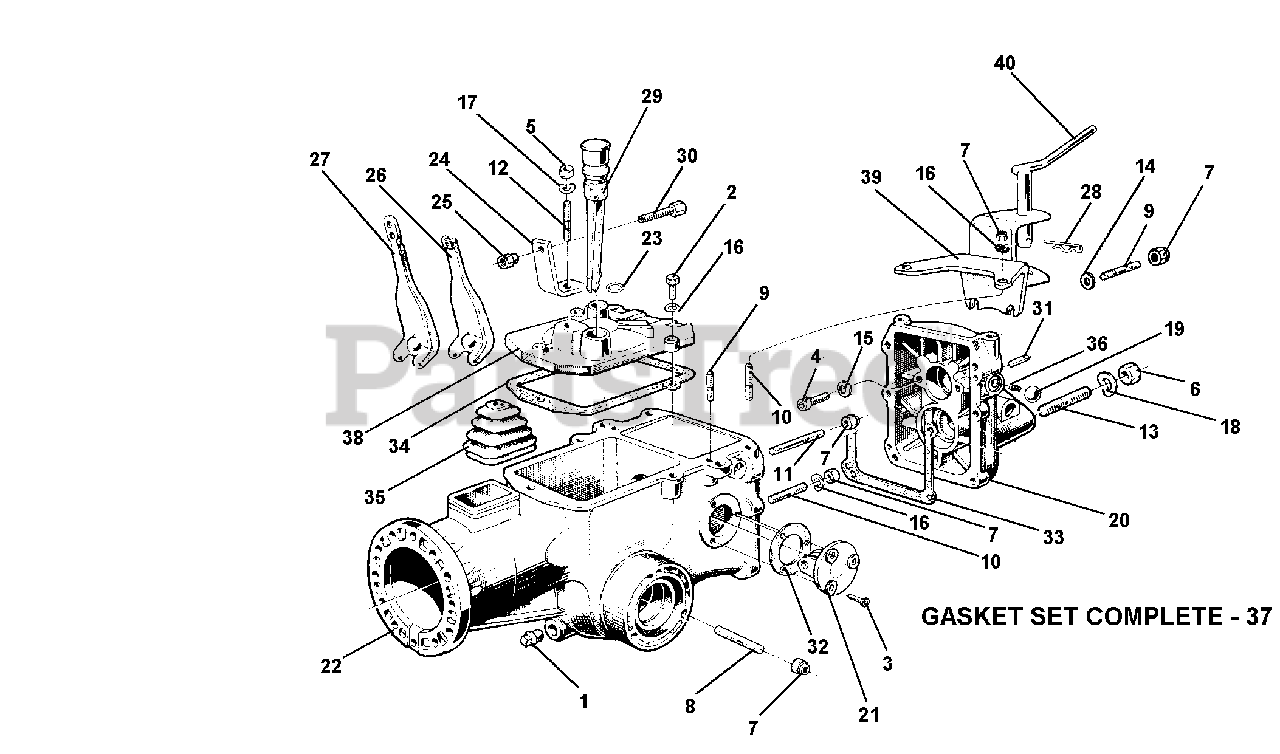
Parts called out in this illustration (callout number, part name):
1	PLUG 1/4 GAS
2	SCREW TE M8 X 30
3	SCREW M6 X 16
4	SCREW TCCEI M8 X 12
6	NUT M12 X 1.25 UNI 5587 6S
7	NUT, SELF LOCKING M8
8	STUD M8 X 46 X 20 X 12
9	STUD M8 X 38 X 14 X 20
10	STUD M8 X 46 X 16 X 16
11	STUD M8 X 58 X 16 X 16
12	STUD M10 X 37 X 19 X 15 8G
13	ST.56XM12X1.25X26XM12X22 8G
14	WASHER, FLAT 8.4
15	SUPER WASHER 8 DIN 6796
16	WASHER, LOCK 8.4
17	WASHER, LOCK 10.5
18	WASHER, LOCK 13
19	BALL 15/32 RIV RB-11.906
20	HOUSING COVER
21	FLANGE, REVERSE SPEED
22	CASING 5 SPEEDS GEARBOX
23	RUBBER RING
24	BRACKET CLUTCH CONTRAST
25	STOP RING NUT
26	CLUTCH LEVER
27	CLUTCH LEVER
29	CAP, WITH MEASURING ROD
30	SCREW, ADJUSTING M8
31	PARALLEL PIN D 6 X 20
33	GASKET, COVER
34	GASKET, COVER
36	P.T.O. SPRING
37	GASEKT SET COMPLETE 735
38	COVER DIFFERENTIAL
39	TOW COUPLING
